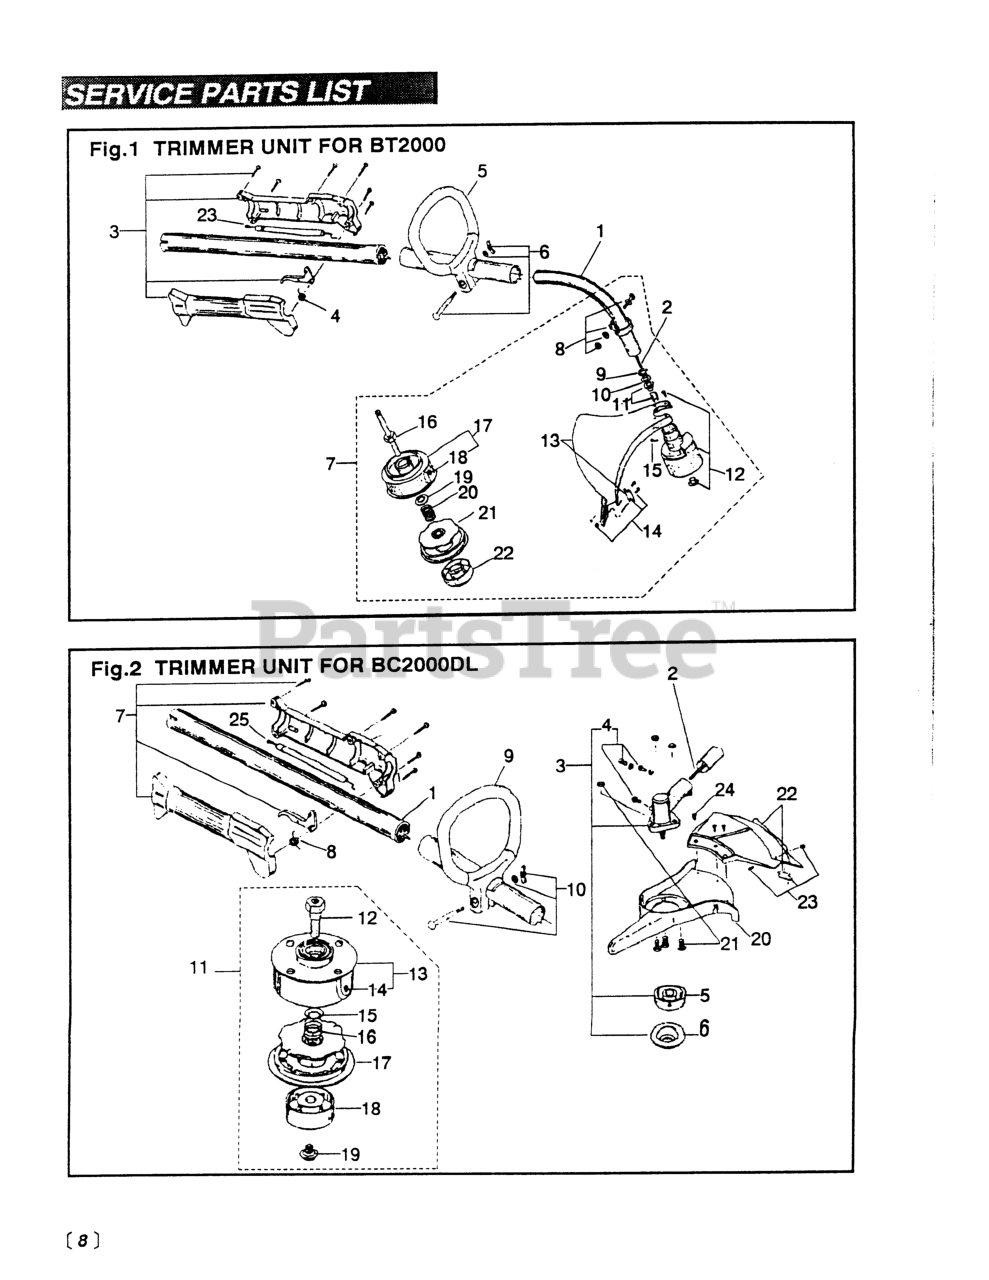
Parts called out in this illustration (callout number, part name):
1	DRIVE SHAFT HSG ASSY (BC)
3	GEARCASE ASSEMBLY
4	HARDWARE, MOUNTING
5	HOLDER (U), BLADE DRIVER
6	HOLDER (L) (RPLS 613222)
8	SPRING, THROTTLE TRIGGER
11	UBT200 - CUTTING HEAD ASSY.
12	SHAFT
13	HOUSING, OUTER SPOOL
14	EYELET
15	WASHER
16	SPRING, INNER REEL
17	REEL, INNER
18	KNOB (USE 180814)
19	KNOB, BUMP HEAD (USE 180814)
20	MOUNT, GUARD
21	GUARD MOUNT HDWE SET
22	GUARD ASSEMBLY
23	BLADE ASSEMBLY
24	SCREW, GUARD MOUNT ASSY
